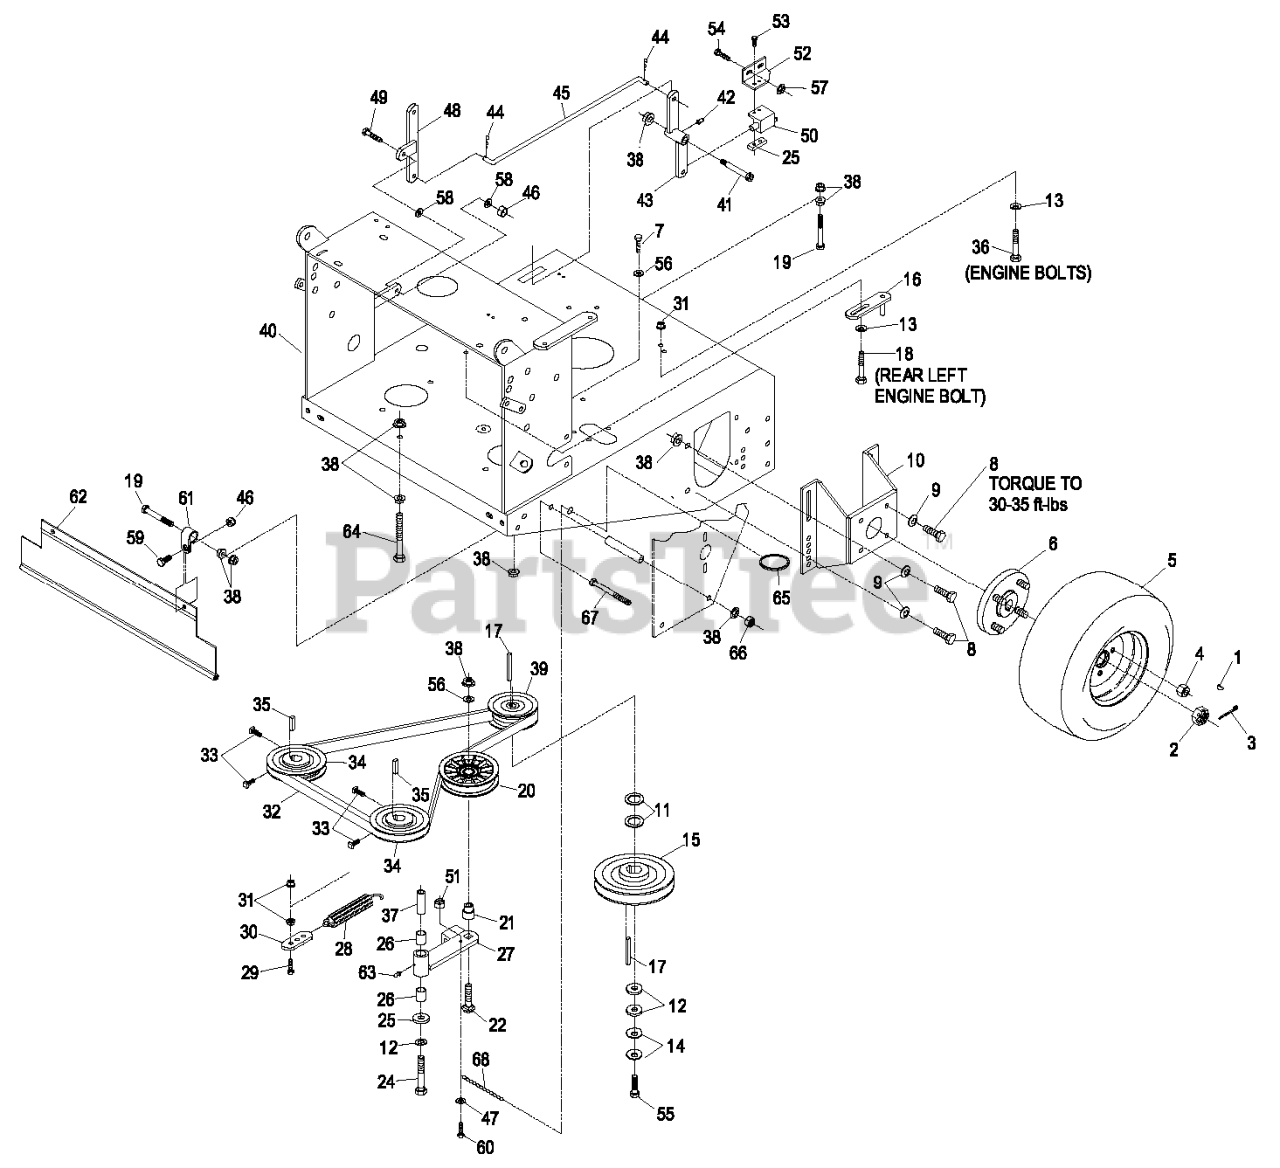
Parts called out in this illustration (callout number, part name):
1	KEY-WOODRUFF
2	NUT-HEX, SLOTTED
3	PIN-COTTER
4	NUT-LUG
5	WHEEL AND TIRE ASM
7	SCREW-HH
8	SCREW-HH
9	WASHER-BELLEVILLE
10	MOUNT-MOTOR
11	WASHER-SPACER
13	WASHER-SPRING
14	WASHER-SPRING
16	GUIDE-BELT
18	SCREW-HH
19	SCREW-HH
20	PULLEY-IDLER, FLAT
21	BUSHING-IDLER
22	SCREW-CARR
23	WASHER-LOCK
24	BOLT-CARR
25	PLATE-TAPPED
26	SLEEVE-BEARING
27	IDLER ARM ASM
28	SPRING-EXTENSION
29	SCREW-HH
30	ANCHOR-SPRING
32	BELT-COG
33	SCREW-SET
34	SHEAVE ASM
36	SCREW-HH
37	BUSHING
38	NUT-HHF, WHIZ
39	PULLEY
40	DECK,ENGINE W/DECALS
42	FITTING-GREASE, 90 DEG
43	BELLCRANK ASM
44	PIN-COTTER
45	LINKAGE-ENGAGE, BLADE
46	NUT-LOCK, NI
47	WASHER-FLAT
49	SCREW-HH
50	SWITCH-OPEN, NORMALLY
51	NUT-LOCK, NI
52	BRACKET-SWITCH, BLADE
53	SCREW-PPH
54	SCREW-HH
55	SCREW-HH
56	WASHER-FLAT
58	WASHER-PLAIN
59	SCREW-HH
60	SCREW-HSH
61	CLIP-LOOM
62	SHIELD-DRAG
63	FITTING-GREASE
64	SCREW-HH
65	RING-SPLIT
66	NUT-LOCK, NI
67	SCREW-HH
68	CHAIN-LINK, TWIST
